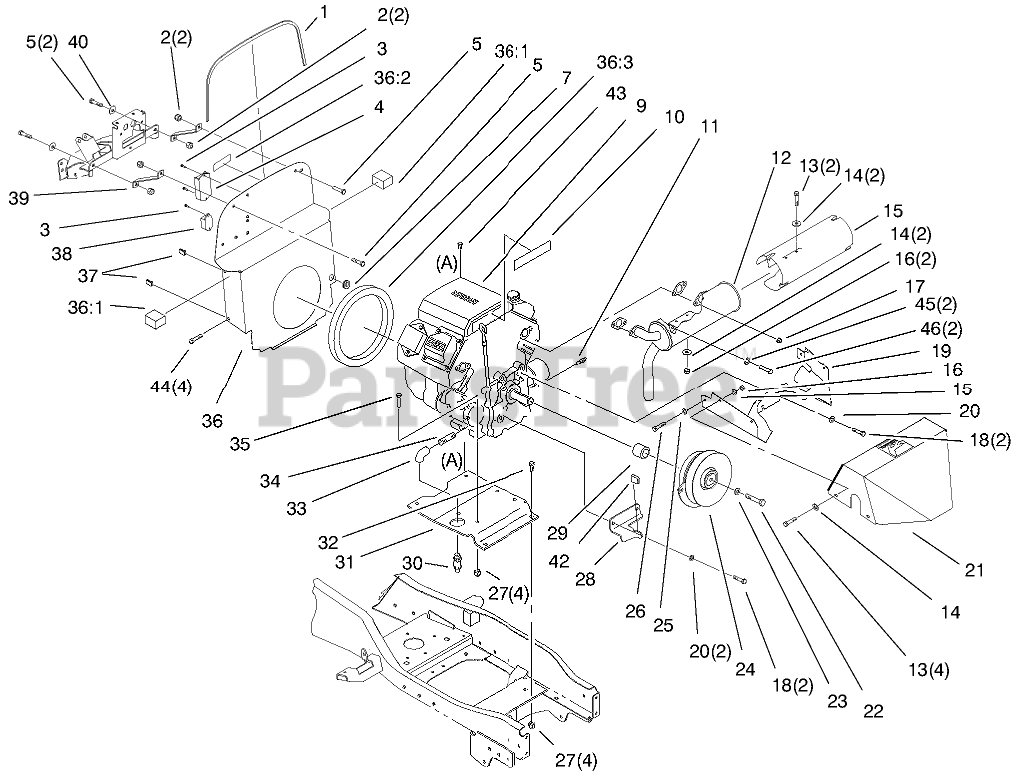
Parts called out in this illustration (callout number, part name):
1	TRIM-LOCK
1	TRIM - LOCK, BULKHEAD
2	NUT-LOCK, NI
3	Screw-Thread Forming (Only On: 73540, 73541)
4	MODULE - KOHLER
5	SCREW-HH
7	GROMMET
10	Decal-18hp Engine (Only On: 73470)
10	Decal-20hp Engine (Only On: 73540, 73541)
11	SENDER-OIL TEMPERATURE
12	MUFFLER
13	SCREW-HH
14	WASHER-FLAT
15	REFLECTOR - HEAT
16	NUT-LOCK, CONE
17	NUT-HF
18	SCREW-HH
19	SHROUD-MUFFLER
20	WASHER-LOCK
21	SHROUD-MUFFLER
22	SCREW-HH
23	WASHER-FLAT
24	CLUTCH-PTO
25	WASHER-LOCK
26	SCREW-HH
27	NUT-LOCK, NI
28	CLUTCH-STOP
29	SPACER-CLUTCH
30	VALVE-DRAIN, OIL
31	PLATE-ENGINE
32	SCREW-HH
33	ELBOW-90 DEGEE
34	NIPPLE
35	SCREW-HH
36	Bulkhead ASM (Only On: 73470, 73540)
36	Bulkhead ASM (Only On: 73541)
36:1	SEAL-FOAM, SIDE
36:2	Decal-Warning (Only On: 73470, 73540)
36:2	Decal-Warning (Only On: 73541)
36:3	SEAL-FOAM
38	Cruise Module (Only On: 73540, 73541)
39	BRACKET-BULKHEAD
40	WASHER-FLAT
42	BUMPER
43	SCREW-TAPTITE
44	SCREW-HH
45	WASHER-LOCK
46	SCREW-HHF
